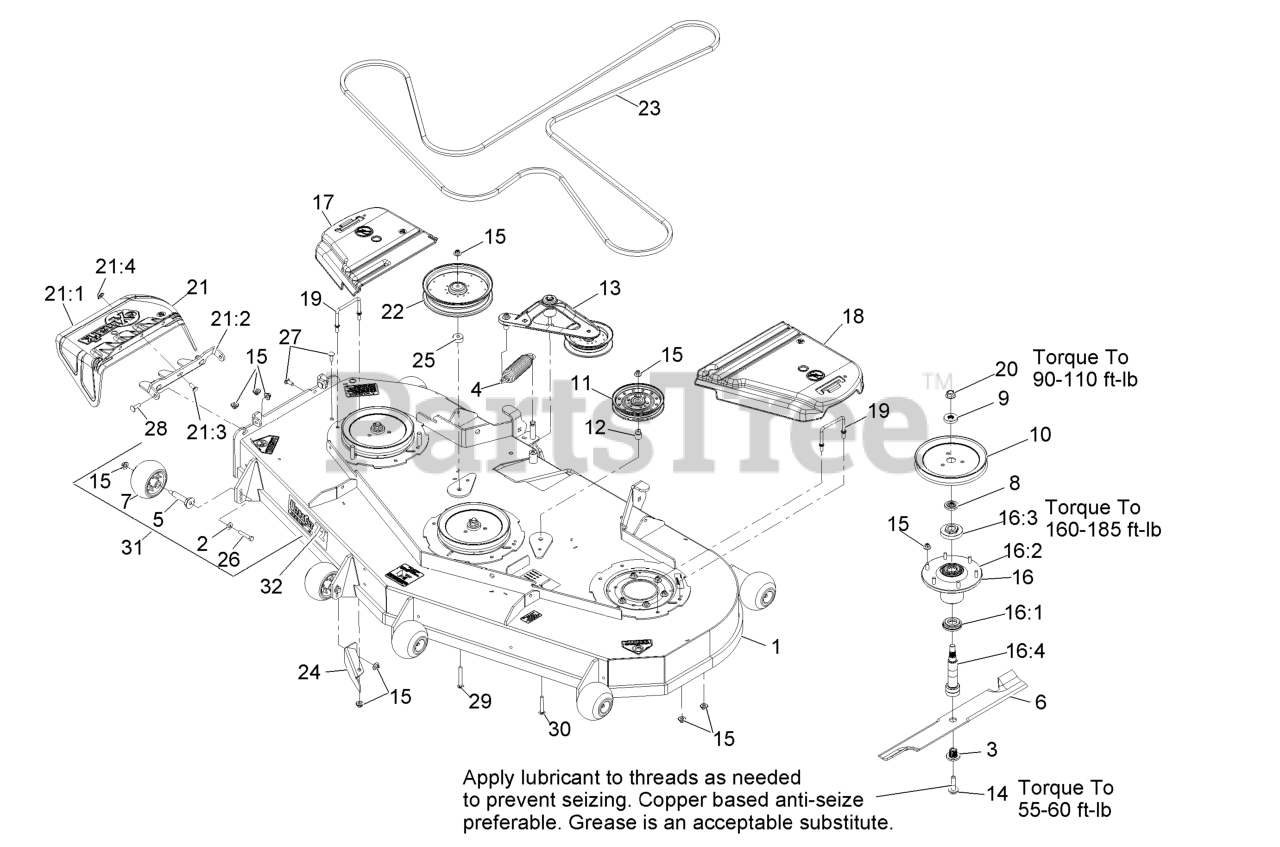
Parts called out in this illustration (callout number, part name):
1	DECK W/ DECALS ASM-72
2	WASHER-BELLEVILLE
3	BUSHING,SPLINED
7	ROLLER-SCALP, ANTI
8	SPACER,SPLINED STEPPED
9	SPACER,SPLINED
10	SHEAVE,BLADE DRIVE 9.00
12	BUSHING-IDLER
13	DECK IDLER ASM
14	SCREW,SEMS 1/2-20 X 2.19
15	Nut-Nyloc 3/8-16 Flg
16	ASM,SPINDLE HOUSING
16:1	GUARD,BOTTOM
16:2	ASM,CUTTER HOUSING
16:3	NUT, SPINDLE 7/8-14
16:4	SPINDLE,DOUBLE SPLINE
17	COVER-BELT, RH
18	COVER-BELT, LH
19	WIREFORM-COVER
20	NUT-FLANGE, CENTERLOCK
21	ASM,DISCHARGE CHUTE
21:1	CHUTE,DISCHARGE
21:2	BRACKET,DISCHARGE CHUTE
21:3	SCREW-CARR
21:4	Nut-Nyloc 3/8-16 Flg
22	PULLEY-IDLER
23	BELT-V
24	BAFFLE,DISCHARGE 726
25	SPACER-IDLER
26	SCREW-HH
27	SCREW-CARR
28	Bolt-Carriage 3/8-16 X 1 1/4
29	SCREW-CARR
30	SCREW-CARR
32	DECAL,ULTRACUT 72 SERIES
